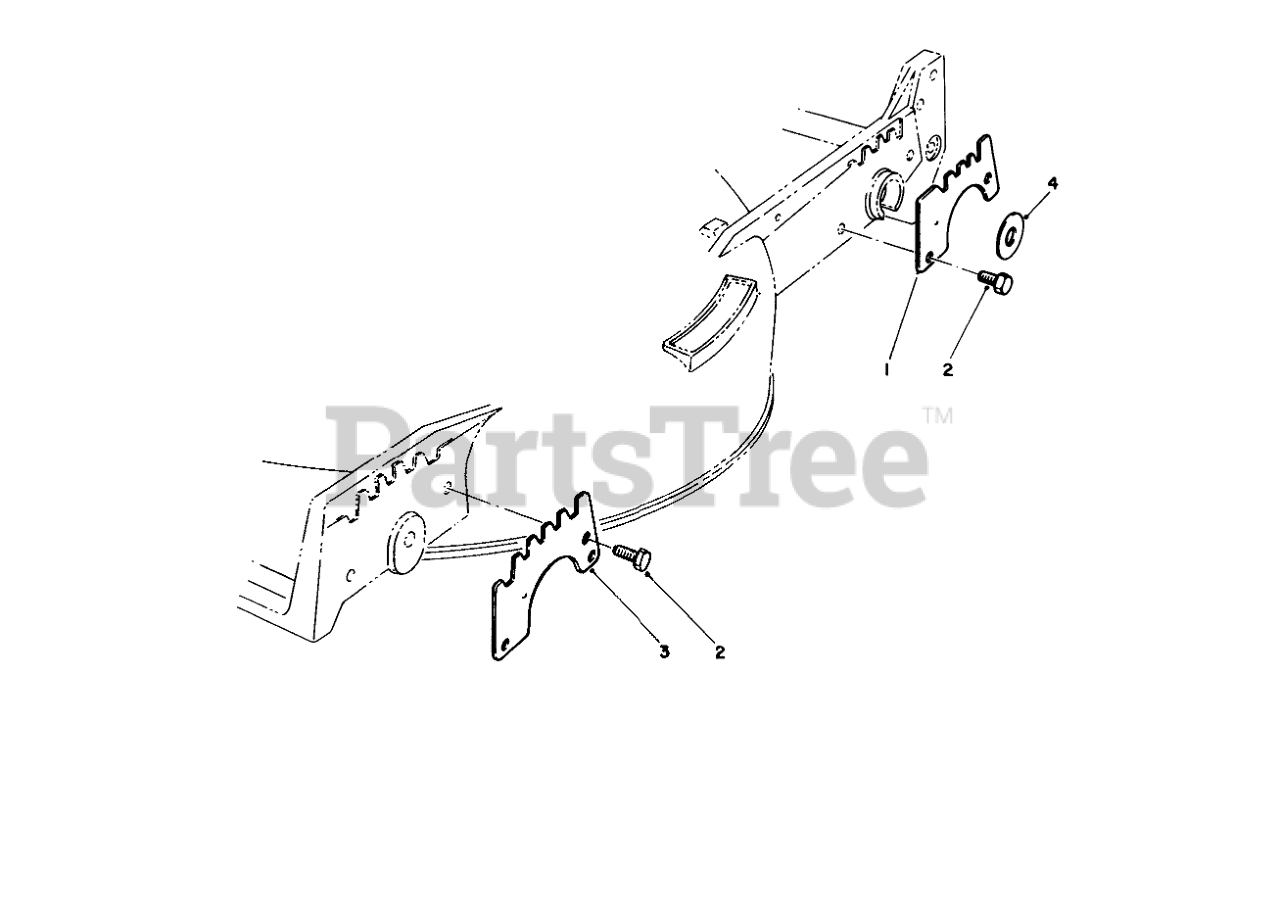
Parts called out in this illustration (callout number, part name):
1	WEAR PLATE,REAR
2	SCREW-HWH
3	WEAR PLATE
4	PIVOT WASHER
